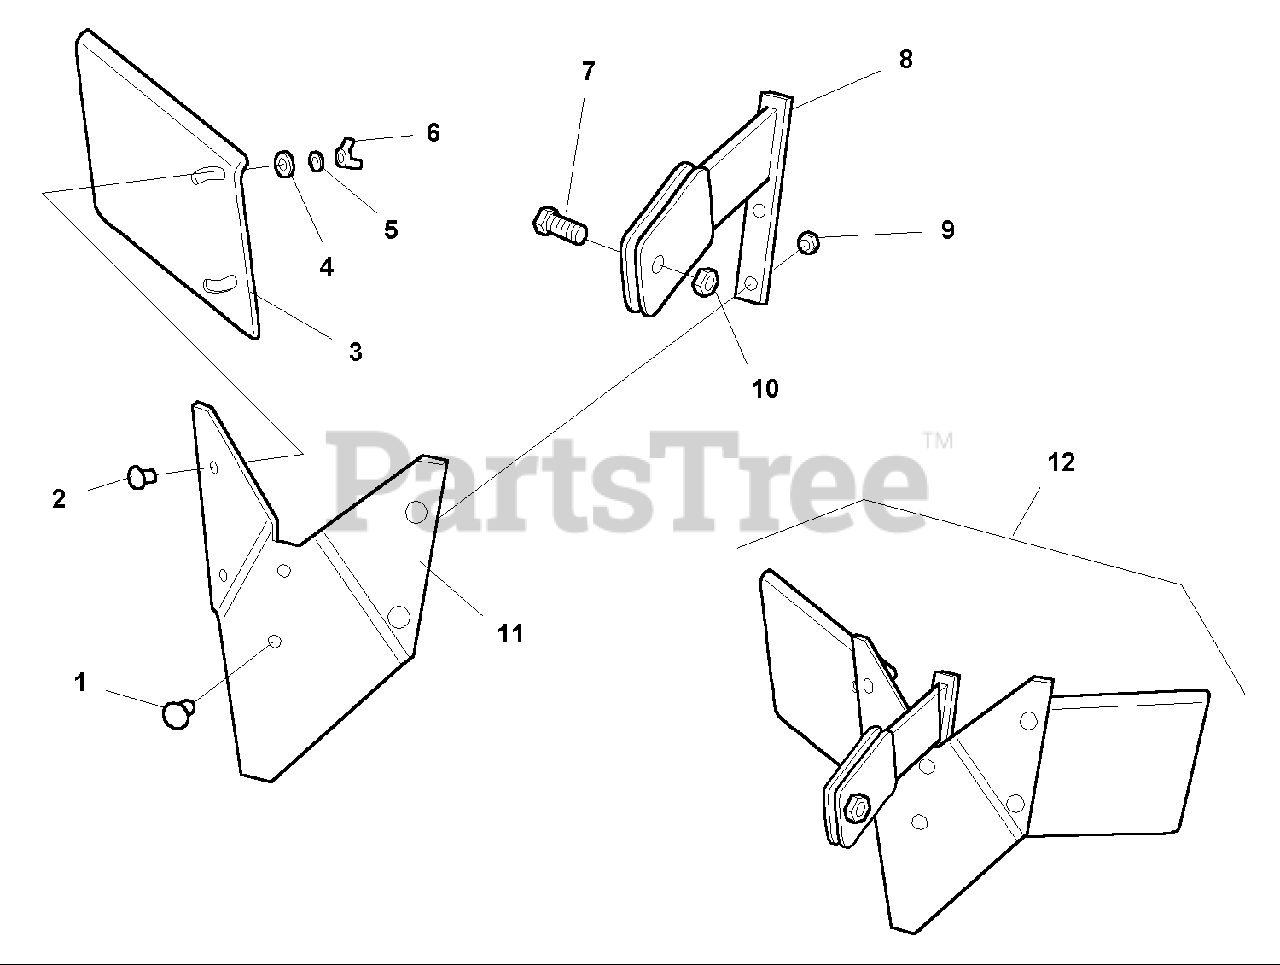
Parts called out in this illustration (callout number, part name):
1	BOLT, Carriage, 3/8-16 x 1-1/2
2	BOLT, Carriage, 5/16-18 x 3/4
3	HILLER WING, Left
4	WASHER, Flat, 5/16
5	LOCKWASHER, External Tooth, 5/16
6	WING NUT, 5/16-18
7	BOLT, Socket Head, 3/8-16 x 1-1/4
8	BRACKET
9	NUT, Nylock, 3/8-16
10	NUT, Hex, 3/8-16
11	BLADE, Furrower
12	HILLER / FURROWER ATTACHMENT, Complete
